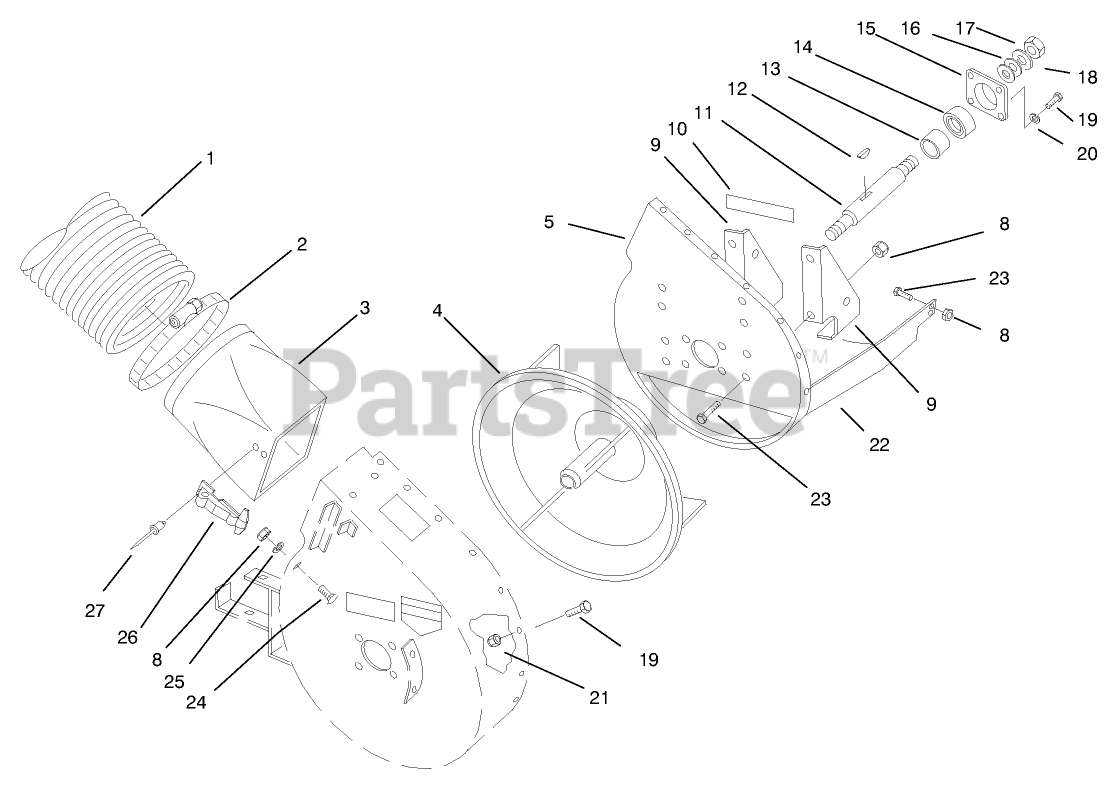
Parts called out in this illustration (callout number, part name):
2	CLAMP
3	ADAPTER
4	IMPELLER - WELDED BLACK
5	MTG PLATE ASM W/DECAL
8	NUT-LOCK, NI
9	BRACKET-BLOWER MT B
10	DECAL
11	SHAFT- BLOWER
13	SPACER
14	BEARING-BALL
15	CUP-BEARING
16	WASHER-FLAT
17	NUT 5/8-11 L.H.
18	WASHER-FLAT
19	SCREW-HH
20	WASHER-LOCK
21	NUT-LOCK, NI
22	DEFLECTOR-W.A. B
23	SCREW-HH
24	BOLT-CARR
25	WASHER-PLAIN
26	HANDLE ASM
27	RIVET-POP
